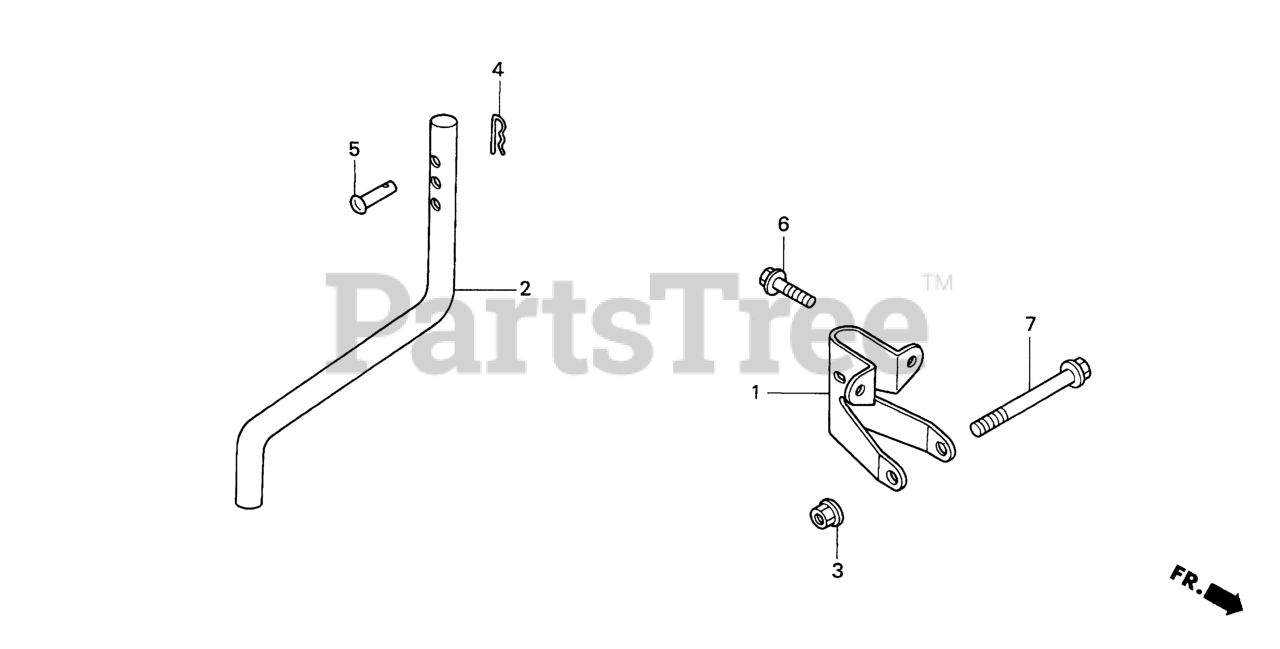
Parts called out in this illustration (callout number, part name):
1	BOX, HITCH
3	NUT, FLANGE (10MM)
4	PIN, SNAP (7MM)
5	PIN (7X48)
6	BOLT, FLANGE (8X25)
7	BOLT, FLANGE (10X80)
